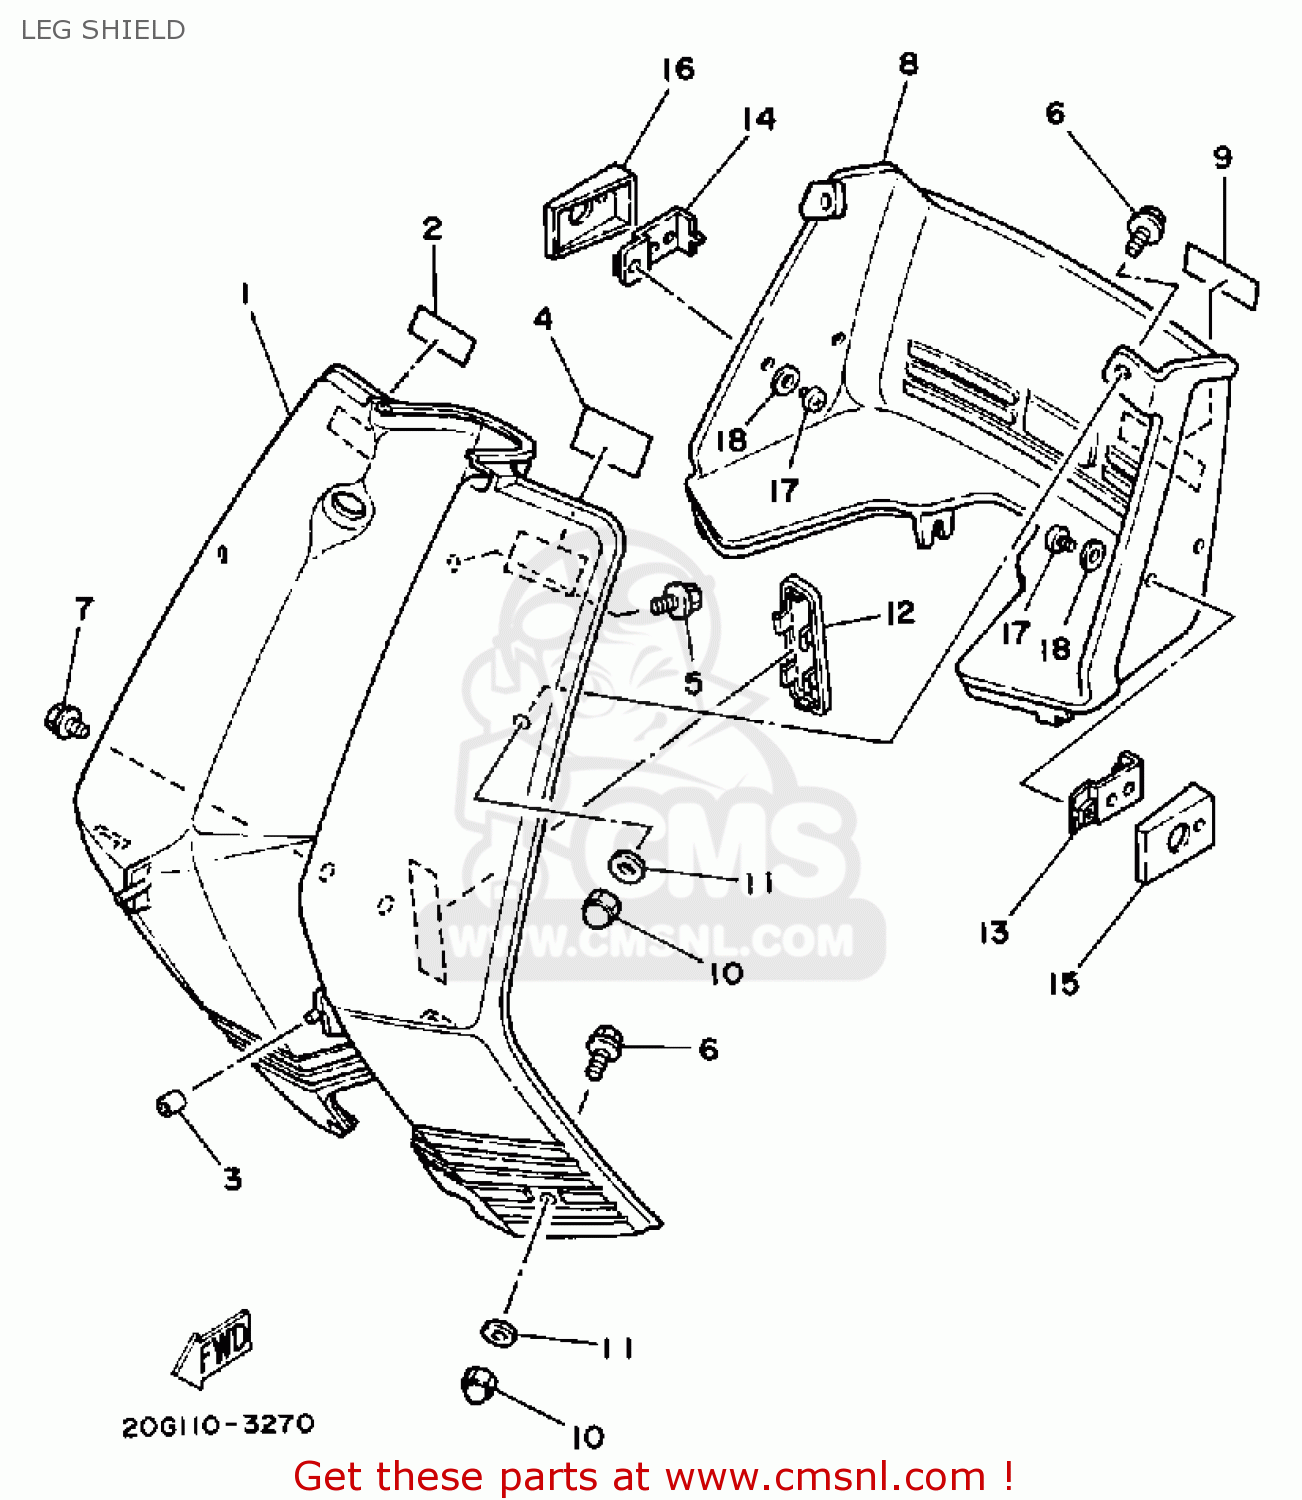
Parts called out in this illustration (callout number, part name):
1	LEG SHIELD 1
2	LABEL, CAUTION
3	HOSE (L11)
4	LABEL, CAUTION
5	BOLT, WITH WASHER (14T)
6	BOLT H/H W/W (EU0)
7	BOLT, WITH WASHER (14T)
8	LID
9	EMBLEM
10	NUT (J17)
11	WASHER, PLATE (25K)
12	CAP
13	BRACKET, REFLECTOR 1
14	BRACKET, REFLECTOR 2
15	COVER, REFLECTOR 1
16	COVER, REFLECTOR 2
17	SCREW, PAN HEAD
18	YBS66-5 WASHER, PLAIN
